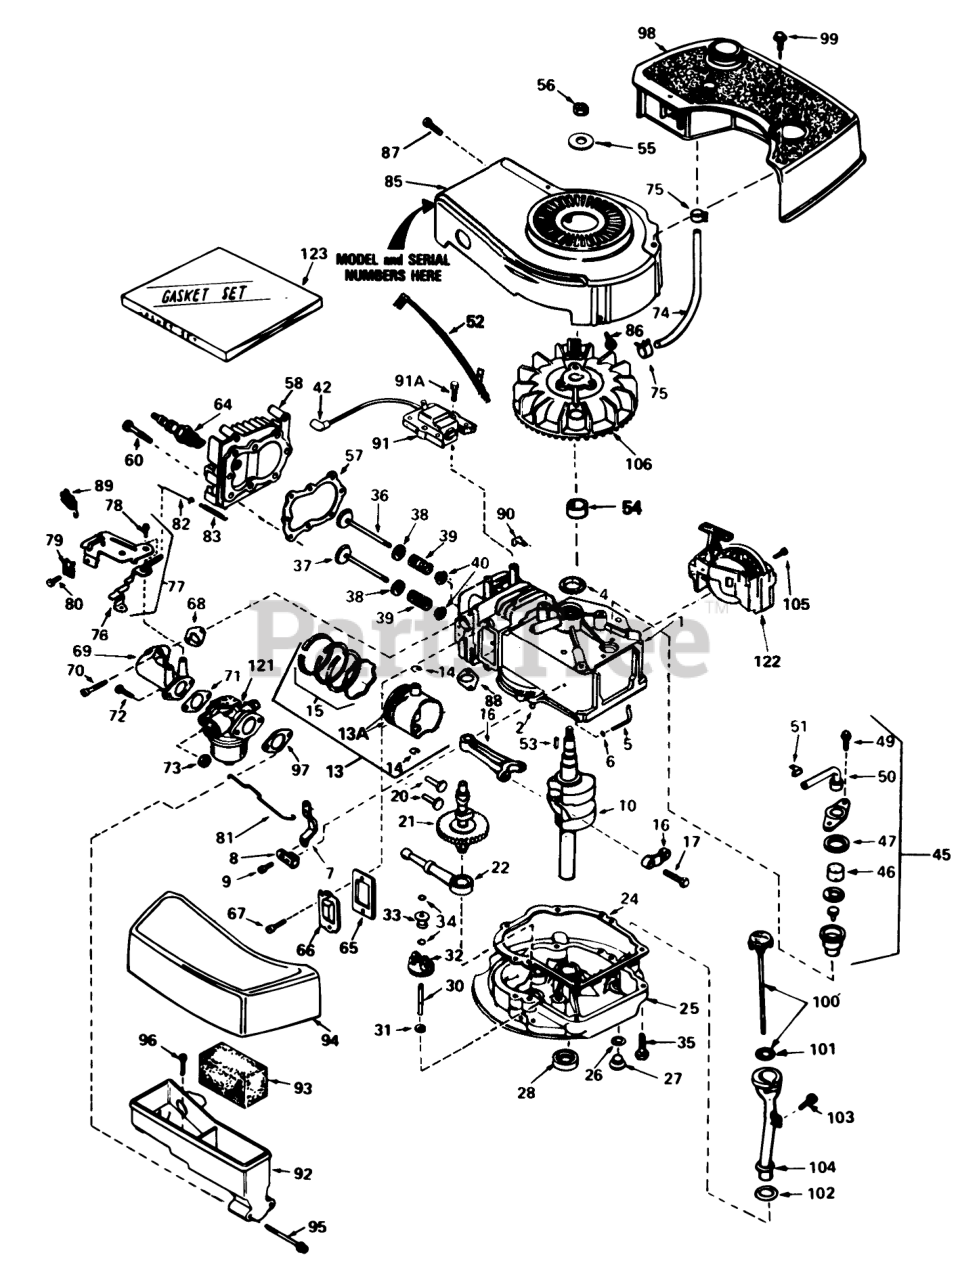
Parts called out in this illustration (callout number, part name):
1	Cylinder Assy. (Incl. #2 & 4)
2	Pin-Dowel
4	Seal-Oil
5	Rod, Governor (Incl. #6)
6	Washer-Flat
7	Governor Lever
8	Clamp-Lever, Governor
9	Screw
10	Crankshaft
13	Piston, Pin & Ring Assy. (Std.) (Incl. #13A, 14 & 15)
13	Piston, Pin & Ring Assy. (.010 oversize) (Incl. #13A, 14 & 15)
13	Piston, Pin & Ring Assy. (.020 oversize) (Incl. #13A, 14 & 15)
13A	Piston & Pin Assy. (Std.) (Incl. #14)
13A	Piston & Pin Assy. (.010 oversize) (Incl. #14)
13A	Piston & Pin Assy. (.020 oversize) (Incl. #14)
14	Ring-Retaining, Piston Pin
15	Ring Set (Std.)
15	Ring Set (.020" OS)
15	Ring Set (.010" OS)
16	Rod Assy., Connecting (Incl. #17)
17	Bolt-Rod, Connecting
20	Lifter-Valve
21	Camshaft(Mech.Comp. Release)
22	Oil Pump ASM
24	Gasket, Mounting
25	Flange Assy., Mounting (Incl. #26 thru 30)
26	Gasket-Oil Drain
27	Plug Oil Drain
28	Seal Oil
30	Shaft-Governor
31	Washer-Flat
32	Gear Assy., Governor (Incl. #31)
33	Spool-Governor
34	Ring-Retaining
35	Screw (1/4-20 x 1-1/4)
36	Valve, Intake (Std.) (Incl. #40)
36	Valve, Intake (1/32" oversize) (Incl. #40)
37	Valve, Exhaust (Std.) (Incl. #40)
37	Valve, Exhaust (1/32" oversize) (Incl. #40)
38	Cap-Upper Valve Spring
39	Spring-Valve
40	Cap-Valve, Spring
42	Cover-Spark Plug
45	Breather Assy. (Incl. #46 thru 51)
46	Element-Breather
47	Gasket-Breather
49	Screw (10-24 x 9/16)
50	Tube, Breaker
51	Clip, Breather
52	Wire-Ground
53	Key-Flywheel
55	Washer-Belleville
56	Nut-Flywheel
57	63573 GIL 42 SNWTHW
58	Head-Cylinder
60	Screw (5/16-18x1-1/2)
64	Plug, Spark (J17LM or equiv.)
64	Plug, Spark (Champion RCJ-8)
65	Gasket-Breather
66	Cover-Valve
68	Gasket-Intake
69	Pipe, Intake (Incl. #68)
70	Screw (1/4-20 x 1)
71	Gasket-Carburetor
72	Screw (1/4-28 x 7/8)
73	Nut and Lock Washer (1/4-28)
74	Line-Fuel
75	Clamp-Line, Fuel
76	Lever Control
77	Control Assy., Speed (Incl. #76, 78 & 89)
78	Screw, Hex Washer Hd Shoulder Self-Tap
79	Conduit
80	Screw (10-32 x 3/8)
81	Link-Throttle
82	Link Governor Spring
83	Spring Governor
85	Housing-Blower
86	Screw (1/4-20x19/32)
87	Screw (10-24 x 9/16)
88	Gasket Exhaust
89	Terminal
90	Clip-Wire
91	Lamination & Coil Assy. (Solid State) (Incl. #42)
91A	Screw
92	Body Air Cleaner
93	Filer, Air
94	Cove, Air Cleaner
95	Screw Fil Hd.
96	Screw, Hex Hd.
97	Gasket-Air Cleaner
98	Tank-Fuel
99	Screw (10-32 x 35/64)
100	Dipstick, Oil (Incl. #101)
103	Screw (10-32 x 1/2)
104	Tube-Oil Fill
105	Screw (1/2-20x5/8)
106	Flywheel
121	Carburetor (Incl. #71)
122	Starter-Sidemount
123	Gasket Set (Incl. items marked )
